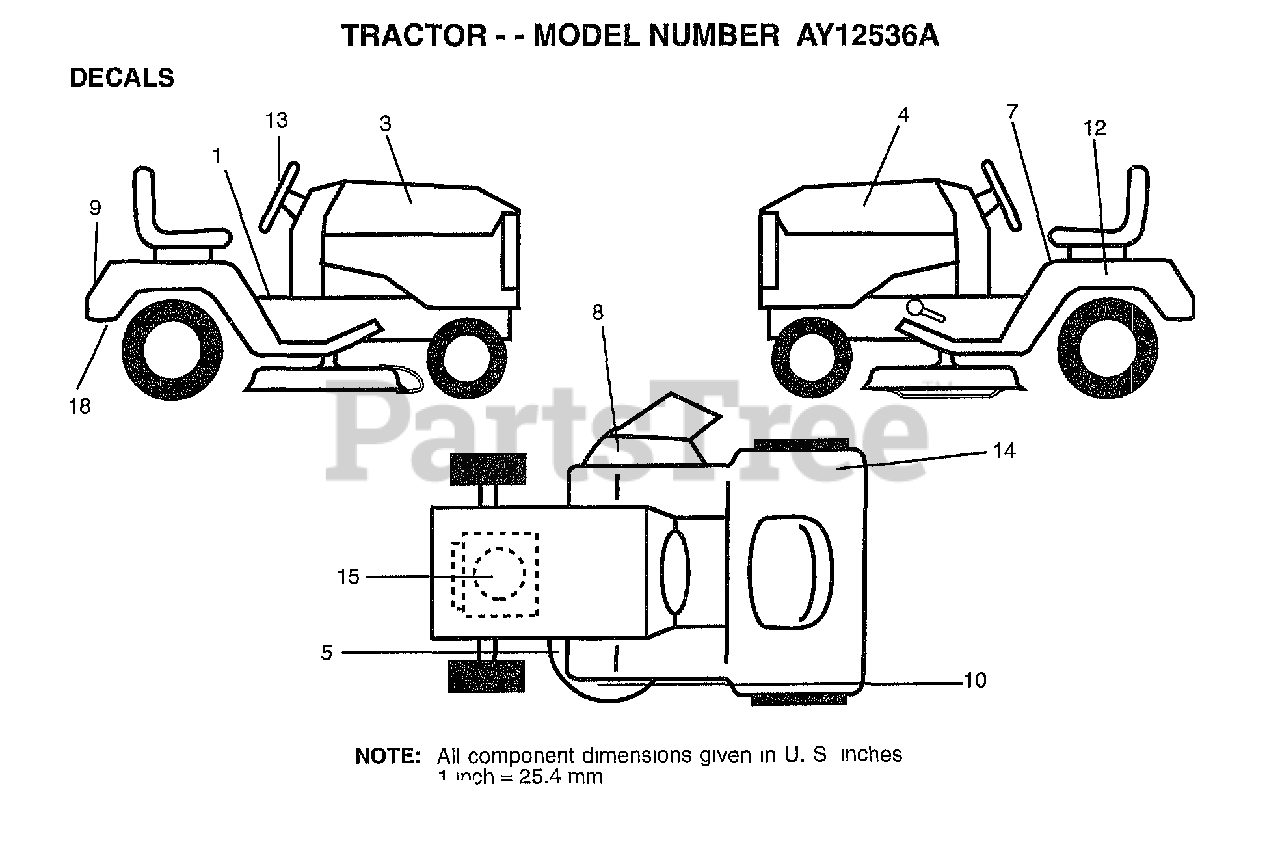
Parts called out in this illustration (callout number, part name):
1	DECAL.OP.INST.SYM
3	"DECAL,HOOD.RH"
4	"DECAL,HOOD,LH"
5	DECAL.V.BELT
7	DECAL.READ.O.MANU
8	DECAL.DANGER.CUTF
9	"DECAL,FENDER"
10	DECAL DECK WIZ +
12	DECAL.BTRY.DANGER
13	"DECAL,INSERT"
15	DECAL, ENGINE
18	DECAL.EURO.ST.CE.
